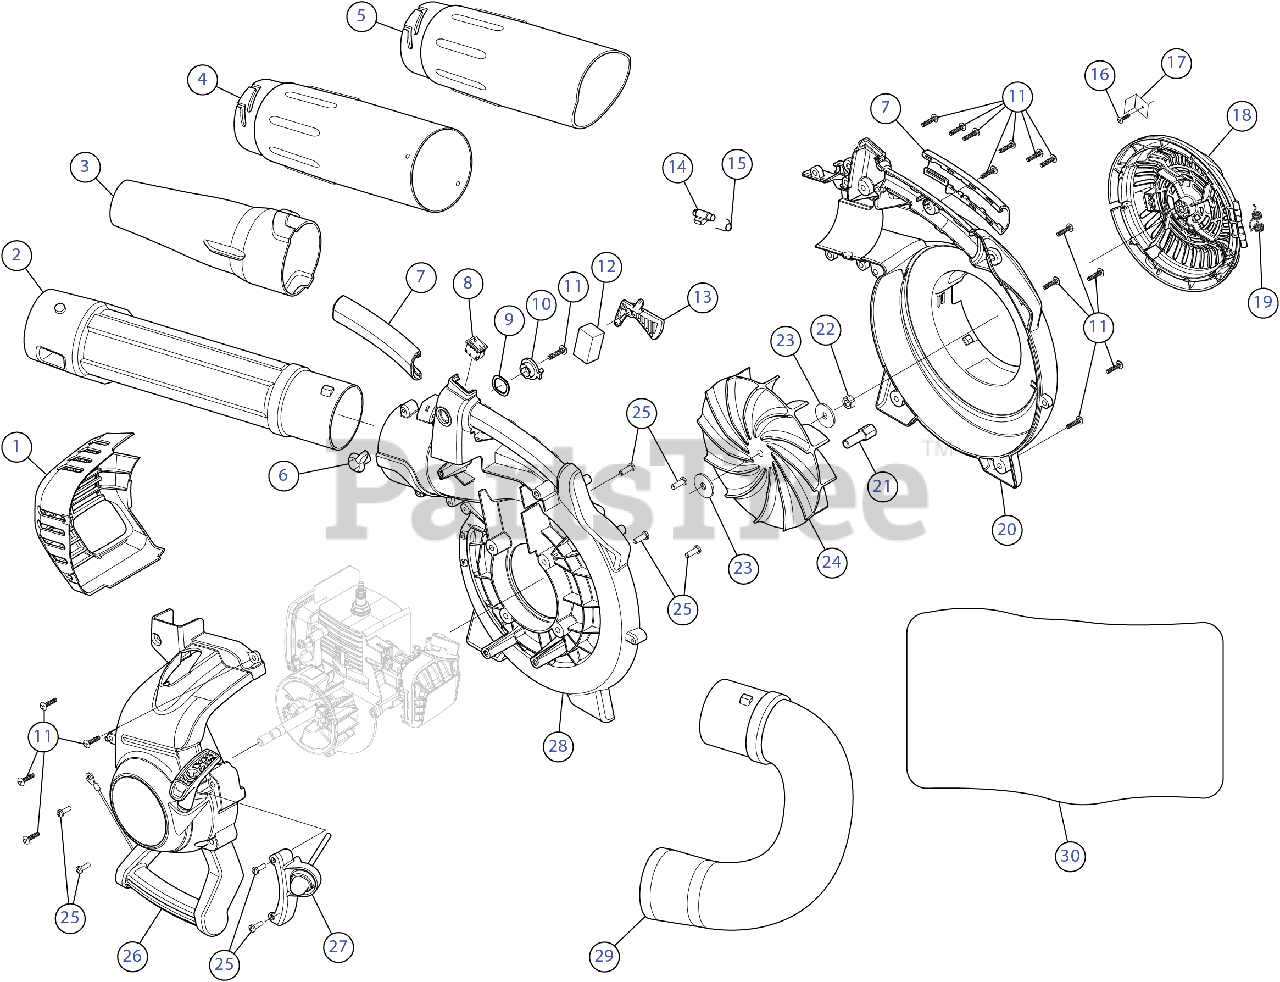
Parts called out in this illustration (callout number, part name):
1	MUFFLER COVER
2	UPPER TUBE
3	NOZZLE BKPK CUB
4	UPPER VAC TUBE SCBLO
5	TUBE, LOWER VACUUM (ELEC BLWR-
6	TRIGGER LOCK OTR
7	ANDLE GRIP ASSEMBLY
8	SW, MOMENTARY ON/O
9	WASHER WAVEY
10	TRIGGER LOCK INR
11	SCREW 1/4-20 x 2.50 GR5
12	AIR FILTER
13	THROTTLE TRIGGER
14	LATCH TUBE
15	SPRING LATCH
16	SCREW-10-9 x .50
17	DOOR LOCK SC
18	INTAKE COVER ASSEMBLY
20	IMPELLER HOUSING OTR
21	ADAPTER STARTER
22	HEX NUT CENTER
23	WASHER FLAT
25	SCREW:10-32X.562:#8P
26	STARTER ASSEMBLY
27	PRIMER BRACKET
28	IMPELLER HOUSING INR
29	ELBOW TUBE
30	VAC BAG SCBLO
